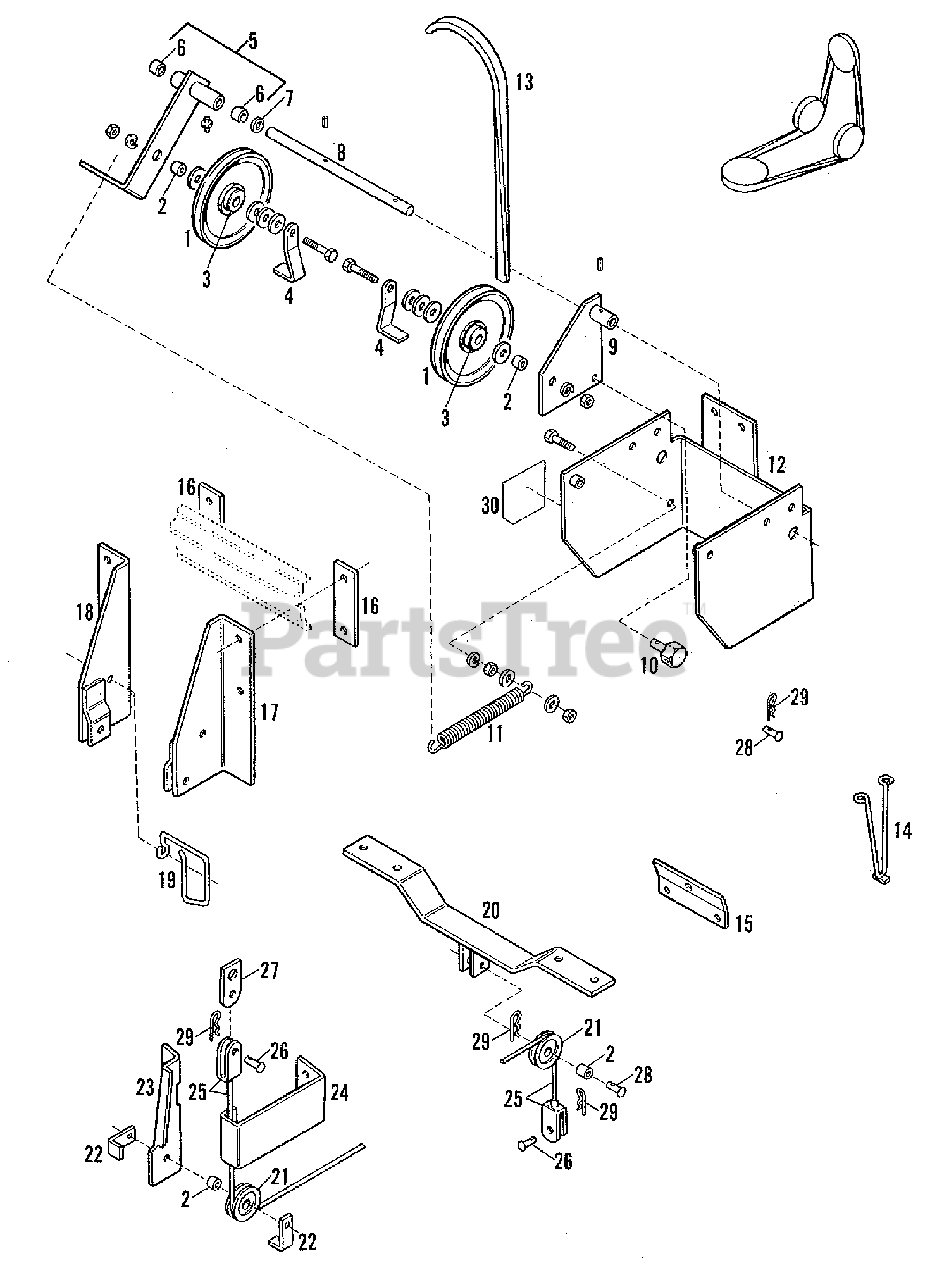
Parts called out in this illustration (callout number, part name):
1	PULLEY ASSEMBLY
4	CAPSCREW, 3/8NC x 2-1/4
4	WASHER, Plain, 7/16 x 1 x 14 GA.
4	LOCKWASHER, 3/8
5	ARM ASSEMBLY
5	FITTING, Lube, 1/4 Str.
7	WASHER, Plain, 41/64 x 1-1/4 x 14 Ga.
8	SHAFT, Idler Support
8	PIN, Spring, 3/16 x 1
9	ARM ASSEMBLY, Support
9	PIN, Spring, 3/16 x 1
10	PIN, Cotter, 3/32 x 1"
11	CAPSCREW, 3/8NC x 1-1/4
11	WASHER, Plain, 7/16 x 1 x 14 GA.
11	LOCKWSHER, 3/8
11	NUT, Lock, 3/8NC
12	SUPPORT ASSEMBLY, Idler
12	CAPSCREW, 7/16NC x 1
12	LOCKWASHER, 7/16
12	WASHER, Plain, 13/32 x 1-1/2 x 11 Ga.
12	NUT, 7/16NC
12	CAPSCREW, 3/8NC x 4-1/4
12	LOCKWASHER, 3/8
13	V-BELT (Use w/Turf Tires)
13	V-BELT (Use w/Agriculture Type Tires)
14	CAPSCREW, 5/16NC x 1-1/2
14	WASHER, Plain, 3/8 x 7/8 x 14 Ga.
14	WASHER, Plain, 13/32 x 1-1/2 x 11 Ga.
14	LOCKWASHER, 5/16
14	NUT, 5/16NC
15	BRACKET, Lift
15	CAPSCREW, 3/8NC x 1
15	LOCKWASHER, 3/8
16	CAPSCREW, 7/16NC x 3-3/4
16	LOCKWASHER, 7/16
16	NUT, 7/16NC
17	HITCH ASSEMBLY, R.H. (Use w/Turf Tires)
17	HITCH ASSEMBLY, R.H. (Use w/Ag. Tires)
18	HITCH ASSEMBLY, L.H. (Use w/Turf Tires)
18	HITCH ASSEMBLY, L.H. (Use w/Ag. Tires)
19	CAPSCREW, 5/16NC x 1
19	WASHER, Plain, 3/8 x 7/8 x 14 Ga.
19	LOCKWASHER, 5/16
19	NUT, 5/16NC
20	BAR ASSEMBLY, Support
20	CAPSCREW, 3/8NC x 1
20	WASHER, Plain, 13/32 x 1-1/2 x 16 Ga.
20	LOCKWASHER, 3/8
22	GUARD, Cable
22	CAPSCREW, 3/8NC x 1-1/2
22	LOCKWASHER, 3/8
23	SUPPORT, Pulley
24	GUIDE, Cable
25	CABLE ASSEMBLY
29	CLIP, Hairpin
30	DECAL, Adjustment
